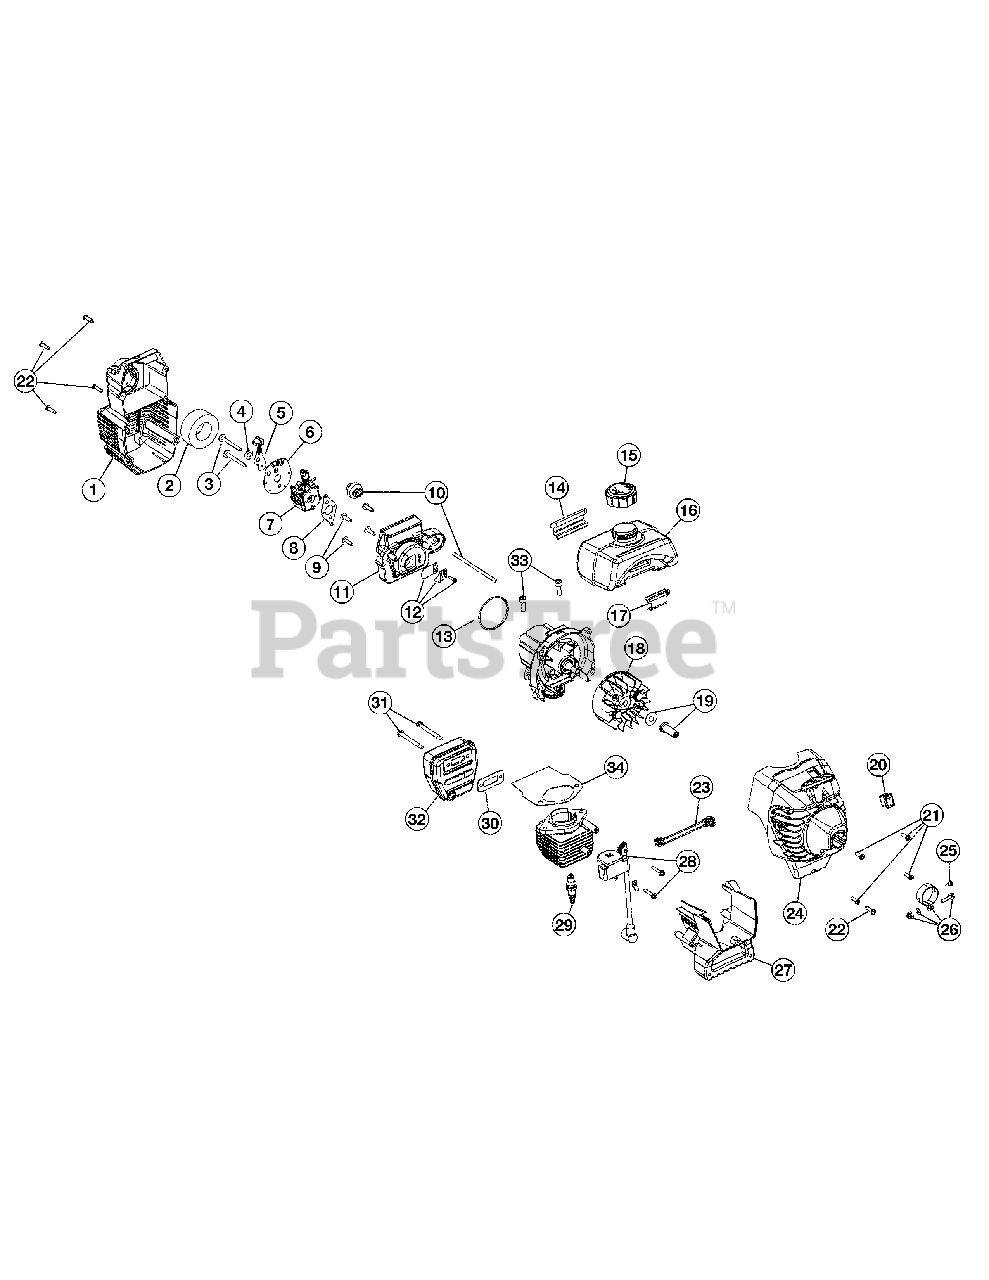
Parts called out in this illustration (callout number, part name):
1	Air Cleaner Cover Assembly (Incl. Ref No. 2 & 22)
2	Air Cleaner Filter
3	Carburetor Mounting Screws
4	Wavey Washer
5	Choke Lever Assembly
6	Choke Lever & Plate (Incl. Ref No. 5)
7	Carburetor Assembly (Incl. Ref No. 8 & 18)
8	Carburetor Gasket
9	Carb Mount Screw
10	Primer and Hose Assembly
11	Carburetor Mount Assembly (Incl. Ref No. 9, 12 & 13)
12	Reed Assembly
13	O-Ring
14	Rear Mounting Pad
15	Fuel Cap Assembly
16	Fuel Tank Assembly (Incl. Ref No. 15)
17	Front Mounting Pad
18	Flywheel Assembly
19	Square Nut Drive
20	Switch Assembly
21	Housing Screw
22	Cover Screw
23	Wire Lead
24	Starter Housing Assembly (Incl. Ref No. 20-23)
25	Anti-Rotation Screw
26	Clamp Assembly (Incl. Ref No. 25)
27	Shroud Extension and Stand (Incl. Ref No. 22)
28	Module Assembly
29	Spark Plug
30	Exhaust Gasket
31	Muffler Mounting Bolt Assembly
32	Muffler Assembly (Incl. Ref No. 30 & 31)
33	Cylinder Bolt
34	Cylinder Gasket
